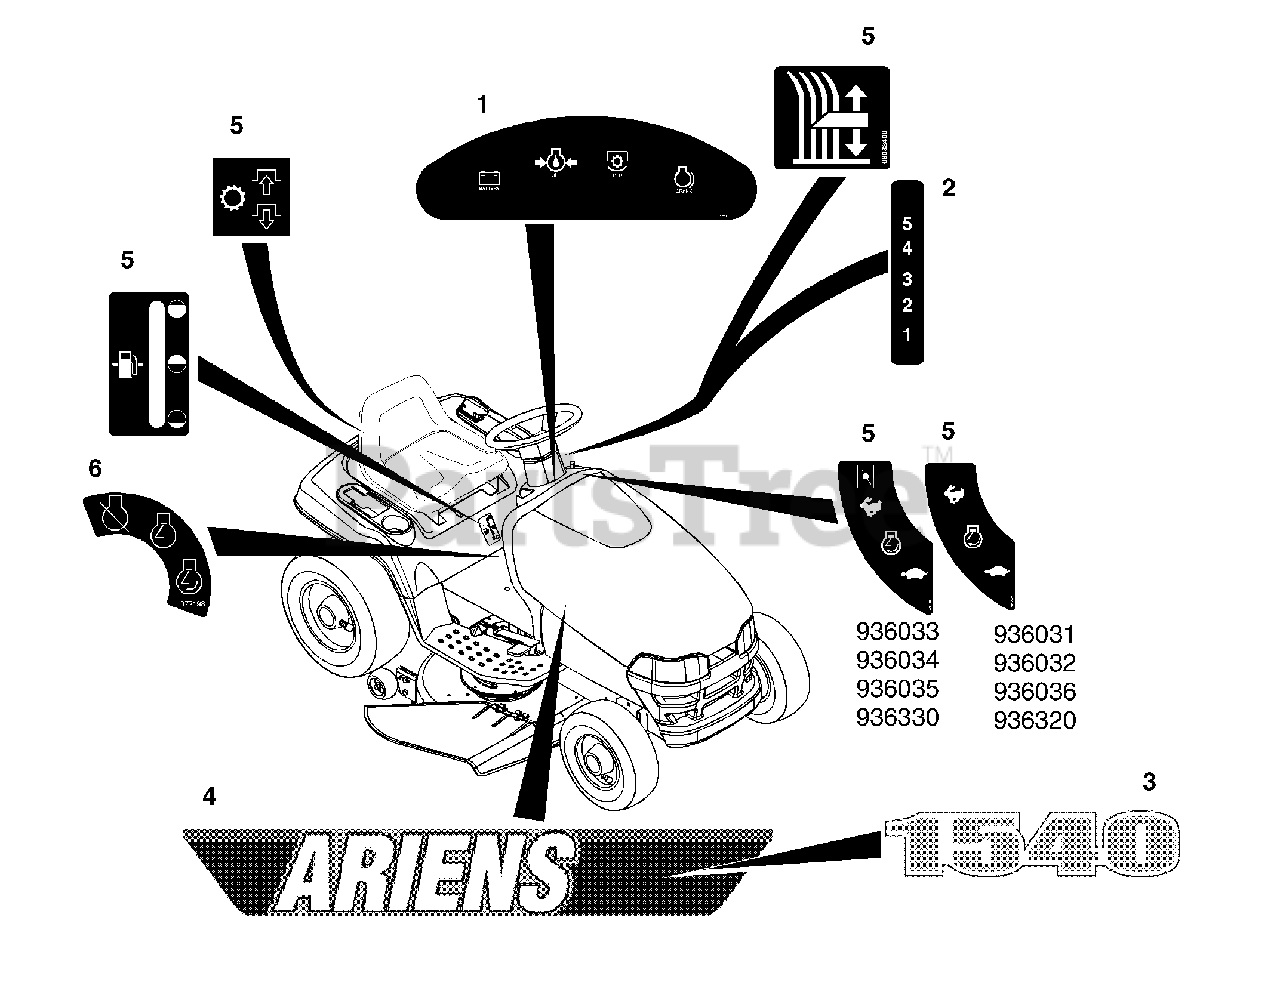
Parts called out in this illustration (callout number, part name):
1	DECAL - DASH W/LIGHTS
2	DECAL, INDICATOR
3	DECAL, HOOD (1540)
4	DECAL-HOOD YT ARIENS
5	SET-YT CONTROLS
6	DECAL - IGNITION
